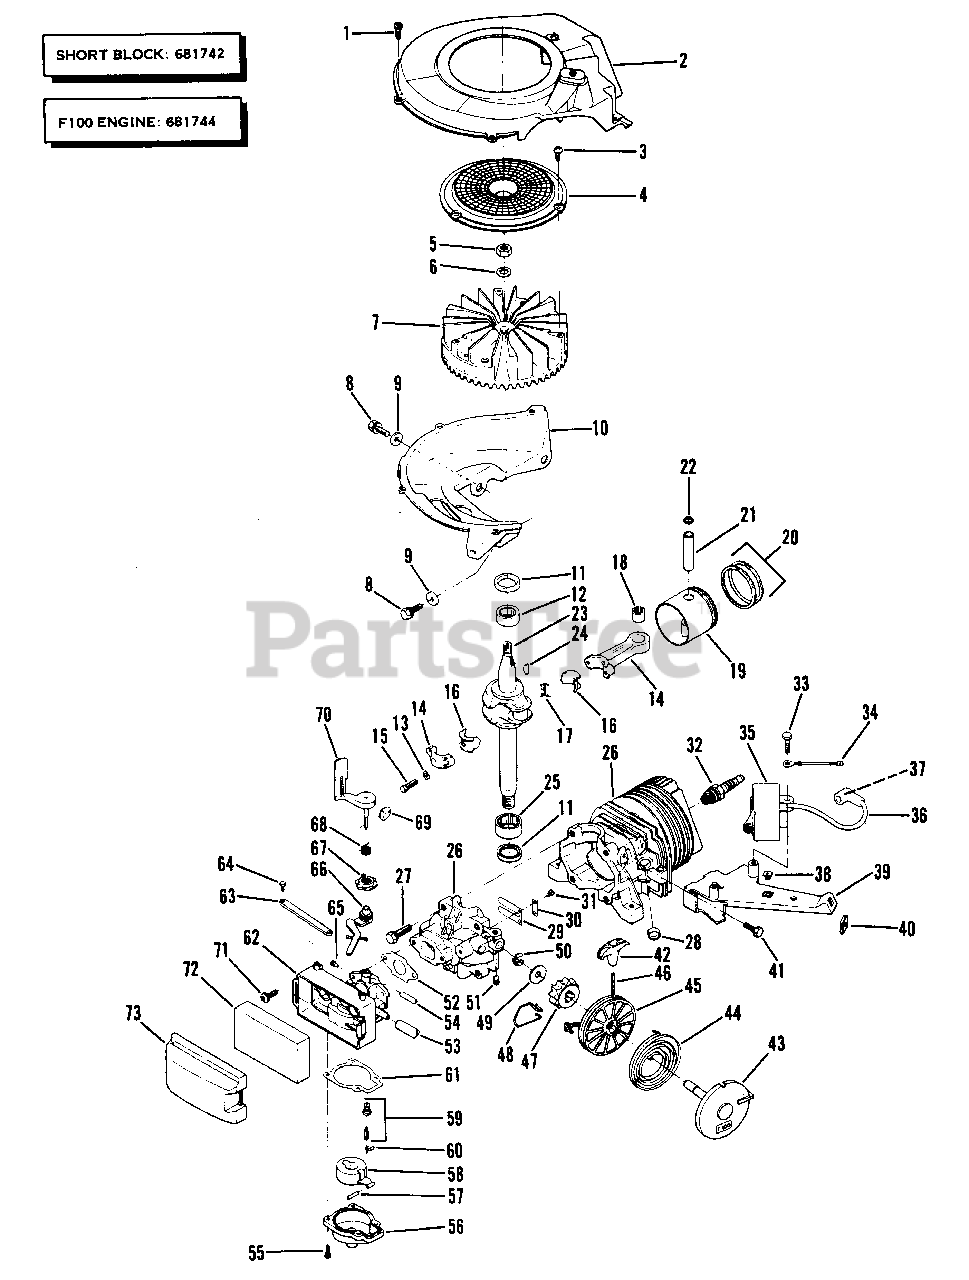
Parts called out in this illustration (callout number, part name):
1	Screw
2	Air Baffle & Eyelet Assembly
3	Screw-Flywheel Screen
4	Screen-Flywheel
5	Nut-Flywheel
6	Lockwasher
7	Flywheel Assembly
8	Screw
9	Washer
10	Base-Shroud
11	Oil Seal
12	Bearing-Upper
13	Lockplate
14	Connecting Rod Assembly
15	Screw
16	Liner-Split
17	Needle Bearing Set
18	Bearing Assembly
19	Piston & Ring Set
20	Ring Set
21	Wrist Pin
22	Retaining Ring
23	Crankshaft
24	Key-Flywheel
25	Bearing-Lower
26	Cylinder & Crankcase Cover Assembly
27	Screw-Cover to Crankcase
28	Plug
29	Reed
30	Plate-Reed Hold Down
31	Screw-Reed to Crankcase Cover
32	Spark Plug
33	Screw-C.D. Mounting
34	Lead Assembly-Ignition
35	C.D. Ignition Module & Lead Assembly
36	High Tension Lead
37	Spring Terminal
38	Grommet-C.D. Bracket
39	Bracket-C.D. Mounting
40	Clip-"U"
41	Screw
42	Handle-Starter
43	Cup & Pin Assembly
44	Spring
45	Pulley
46	Rope
47	Pinion
48	Spring
49	Washer
50	Retainer
51	Set Screw-Starter Assembly
52	Gasket-Carburetor to Crankcase Cover
53	Fuel Line
54	Tube-Primer
55	Screw-Float Chamber
56	Float Chamber
57	Pin-Float
58	Float
59	Float Valve & Seat
60	Clip
61	Gasket
62	Carburetor Body
63	Retainer-Speed Control Lever
64	Screw
65	Screw-Altitude Adjustment
66	Speed Control Lever
67	Collar
68	Spring
69	Disk-Throttle
70	Air Vane & Shaft
71	Screw-Carburetor Mounting
72	Element-Air Filter
73	Cover-Air Filter
